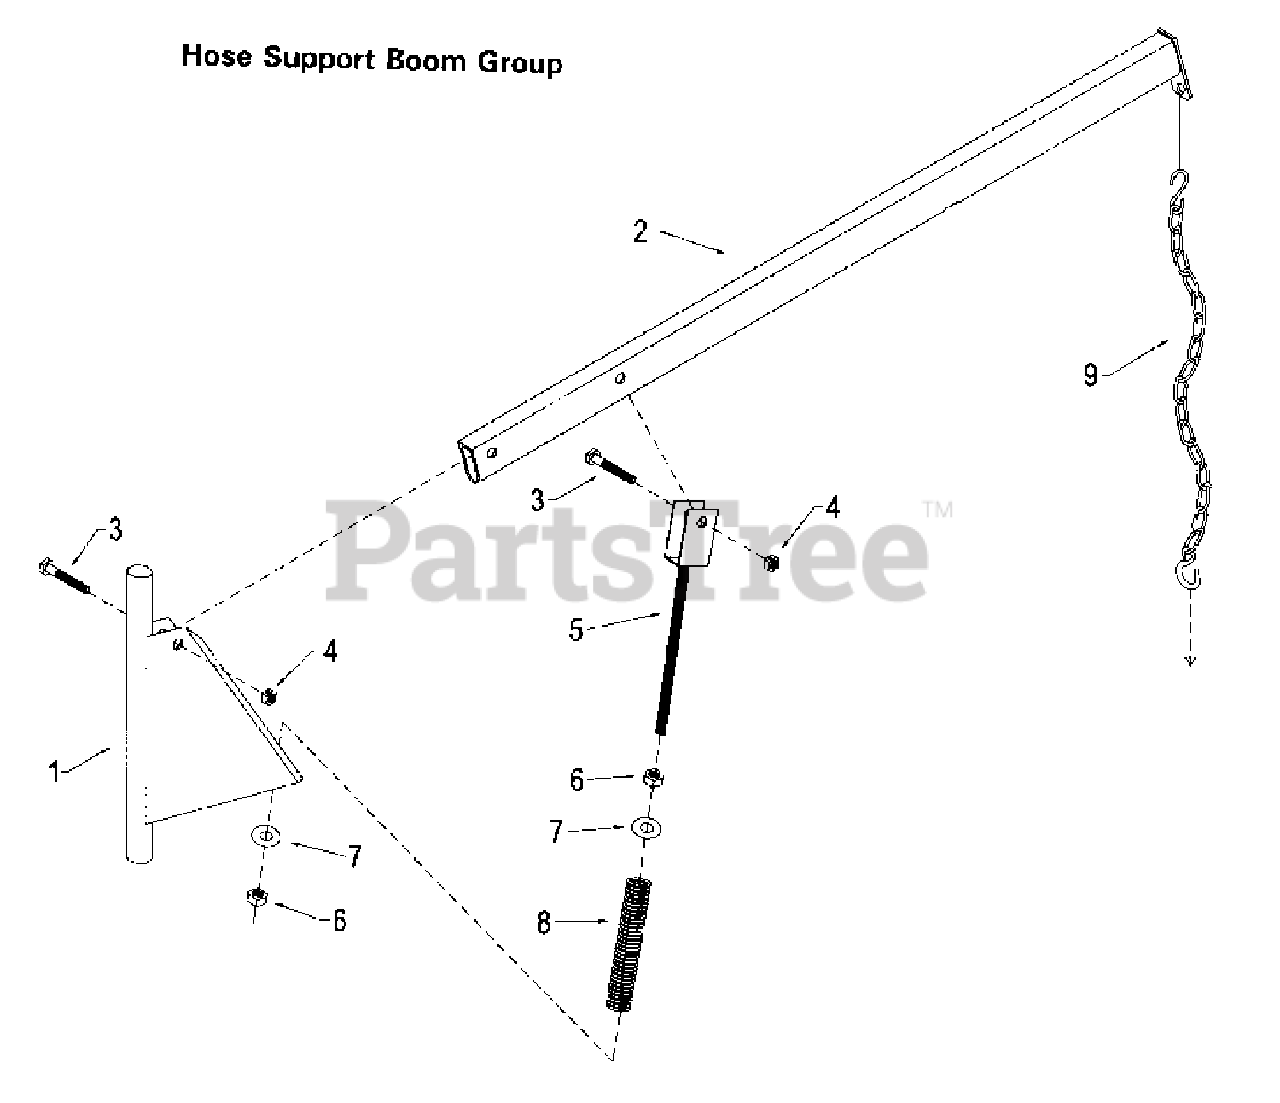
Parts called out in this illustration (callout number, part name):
1	Boom Vertical Member
2	Boom Horizontal Member
3	1/2-13 x 3" Hex Bolt
4	1/2-13 Lock Nut
5	Guide, Threaded Spring
6	3/4-10 Hex Nut
7	3/4 Flat Washer
8	Spring, Boom
9	Chain, Boom w/2 S-Hooks
